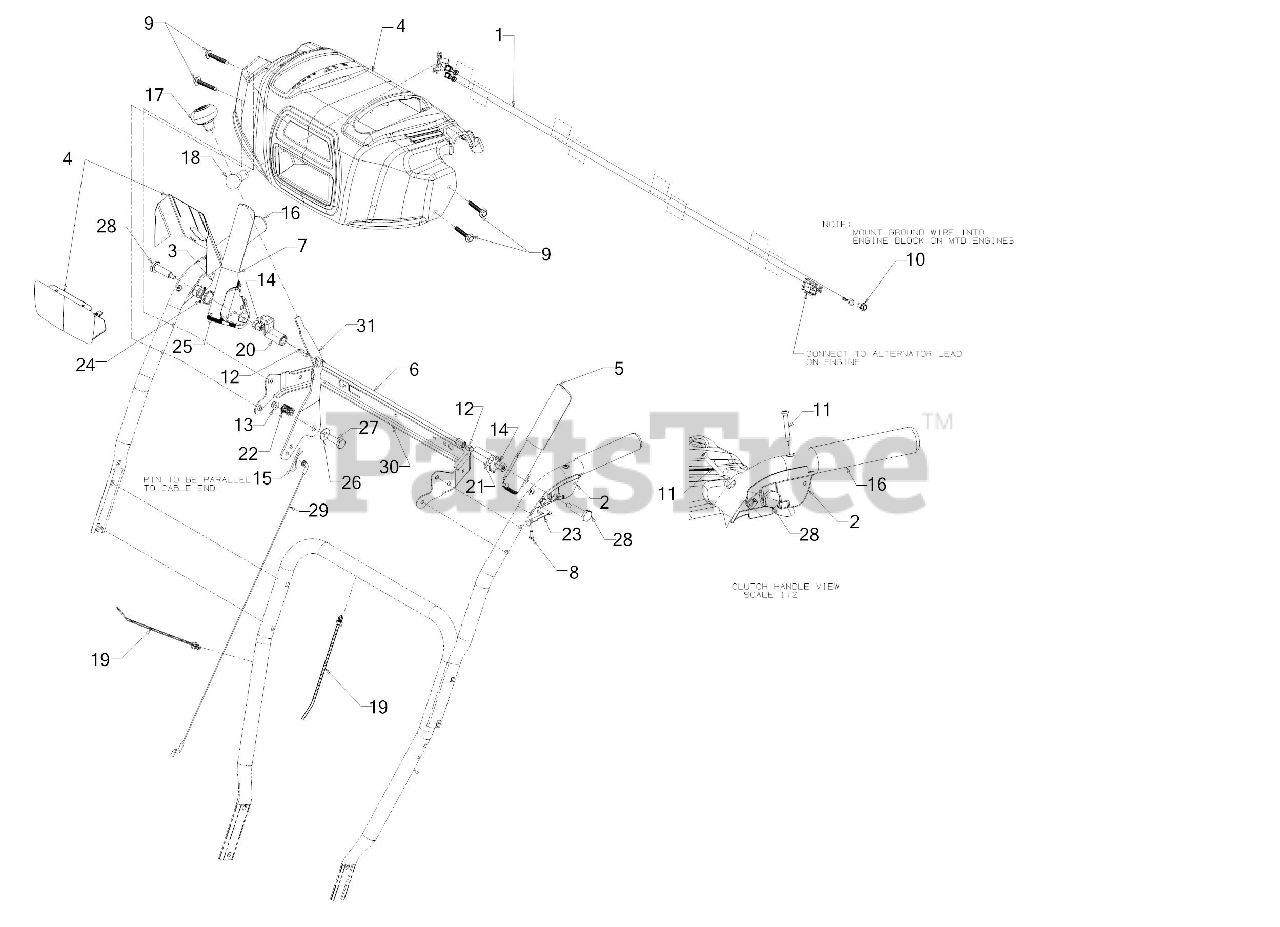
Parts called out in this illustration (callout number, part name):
1	LIGHT HARNESS ASSEMBLY
2	CLUTCH LOCK HANDLE ASSEMBLY (LH)
3	CLUTCH LOCK HANDLE ASSEMBLY (RH)
4	HANDLE PANEL ASSEMBLY
5	HANDLE ASSEMBLY (LH)
7	HANDLE ASSEMBLY (RH)
8	SCREW #8-16 x .50
9	SCREW 1/4-20 x 1.625
10	SCREW 1/4-20 X.500
11	SCREW #10-24 x 1.375
12	SCREW 1/4-20 x .50
13	FLANGE LOCK NUT
14	HEX NUT W/PATCH
15	INTERNAL COTTER PIN
17	SHIFT KNOB
19	PUSH MOUNT TIE
21	CLUTCH LOCK CAM
22	COMPRESSION SPRING
23	CLUTCH SPRING
24	TORSION SPRING
25	RUBBER BUMPER
26	FLAT WASHER
27	SHOULDER SCREW
28	SHOULDER SCREW .437 x 1.345 1/4-20
29	SPEED SELECTOR CABLE (PLASTIC)
30	HANDLE SUPPORT BRACKET
